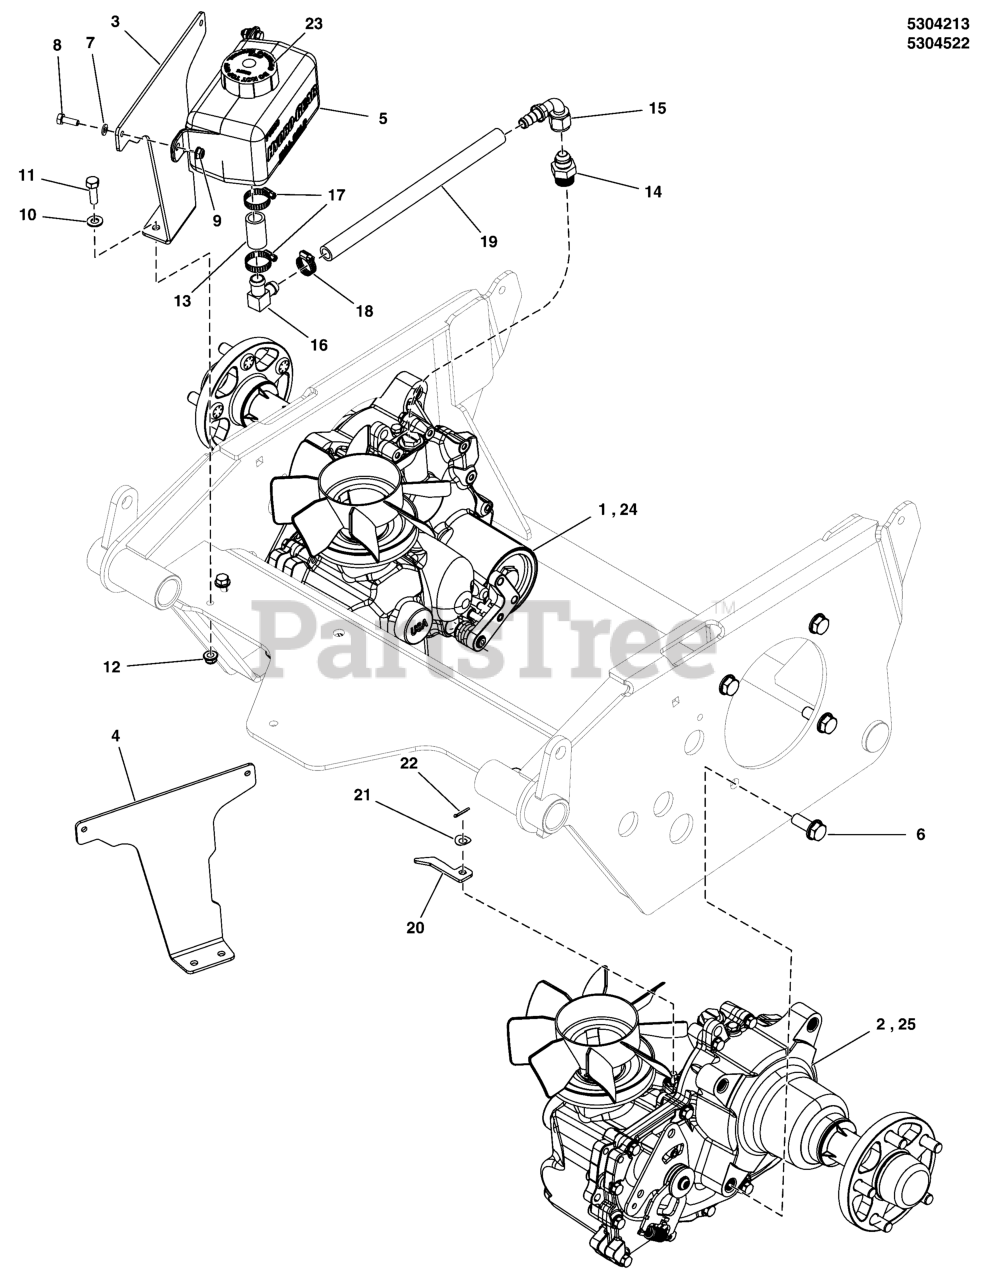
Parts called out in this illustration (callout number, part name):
1	TRANSAXLE
2	TRANSAXLE
3	MOUNT, HYDRO RES, RH - BLK
4	MOUNT, HYDRO RES, LH - BLK
5	HYDRO TANK, HYDRO-GEAR 71938, 1 LITER
6	BOLT, 1/2-13 X 1-1/4, SF, PLT W/PATCH
7	WASHER, 1/4 SAE
8	BOLT, 1/4-20 X 3/4 GD5 CZ
9	NUT, 1/4-20 HEX NYLOCK FLANGE
10	WASHER, 5/16" SAE
11	BOLT, 5/16-18 X 1 GD5 CZ
12	NUT, 5/16-18 HEX NYLOCK FLANGE
13	HOSE, 5/8, PUSH-LOCK, 1.75"
14	FITTING, #10 O-RING X #8 JIC, STR
15	FITTING 90 DEG JIC TO HOSE #8
16	(C) FITTING, DAPCO 1/2
17	CLAMP, #10 HOSE, STAINLESS
18	CLAMP, #6 HOSE, STAINLESS
19	HOSE, 1/2" PUSH-ON, 18.00"
20	ARM, TRANSAXLE RELEASE, ZT4400
21	WASHER,WAVE,M10
22	PIN, 3/32 X 0.750, COT, ZINC/CLEAR
23	RESERVIOR CAP
24	TRANSAXLE
25	TRANSAXLE
